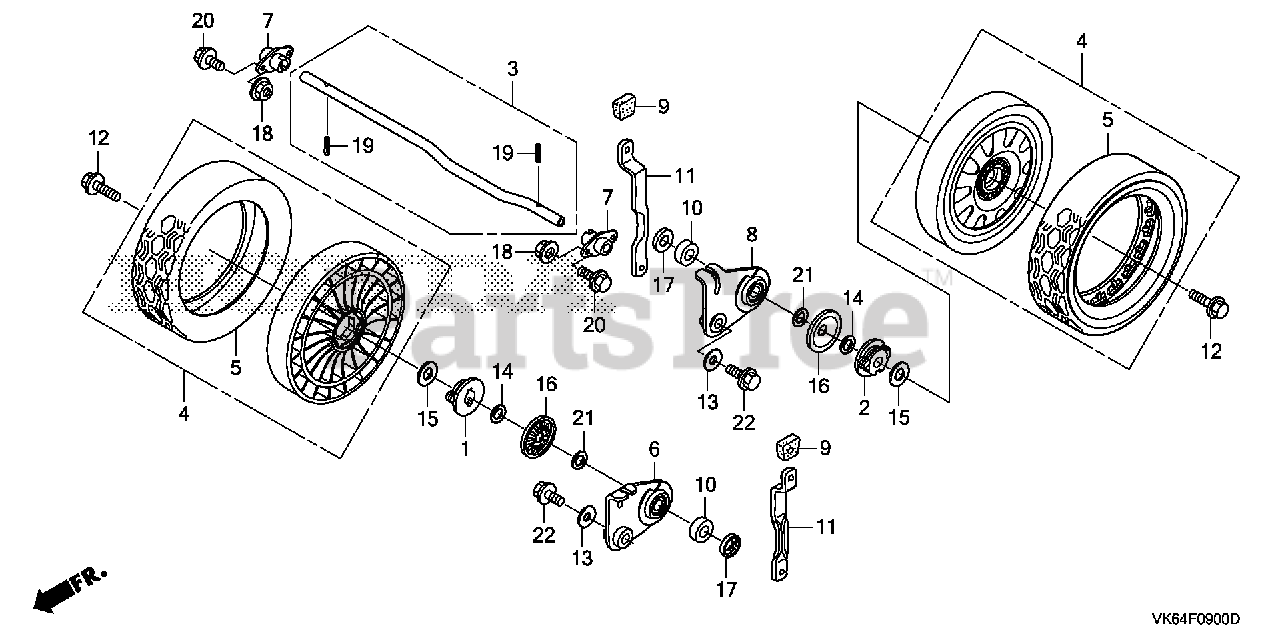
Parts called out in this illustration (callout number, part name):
1	HOLDER, R. RATCHET
2	HOLDER, L. RATCHET
3	SHAFT, RR. AXLE
4	WHEEL ASSY., RR. *NH462R* (VINTAGE GRAY SOLID)
5	TIRE (9 INCH)
6	ARM, R. RR. ADJUSTING
7	HOLDER, RR. AXLE
8	ARM, L. RR. ADJUSTING
9	GRIP, ADJUSTER
9	GRIP, ADJUSTER *NH105* (MAT BLACK)
10	COLLAR, DUST SEAL
11	PLATE, RR. ADJUSTER
12	BOLT, WHEEL
13	WASHER, RR. ENGINE MOUNTING
14	WASHER, PLAIN (15MM)
15	WASHER (16MM)
16	SEAL, RR. WHEEL
17	COLLAR, FINAL SHAFT
18	NUT, FLANGE (6MM)
19	PIN, SPRING (5X25)
20	BOLT, FLANGE (6X12)
21	WASHER, PLAIN (15MM)
22	BOLT, FLANGE (8X16)
